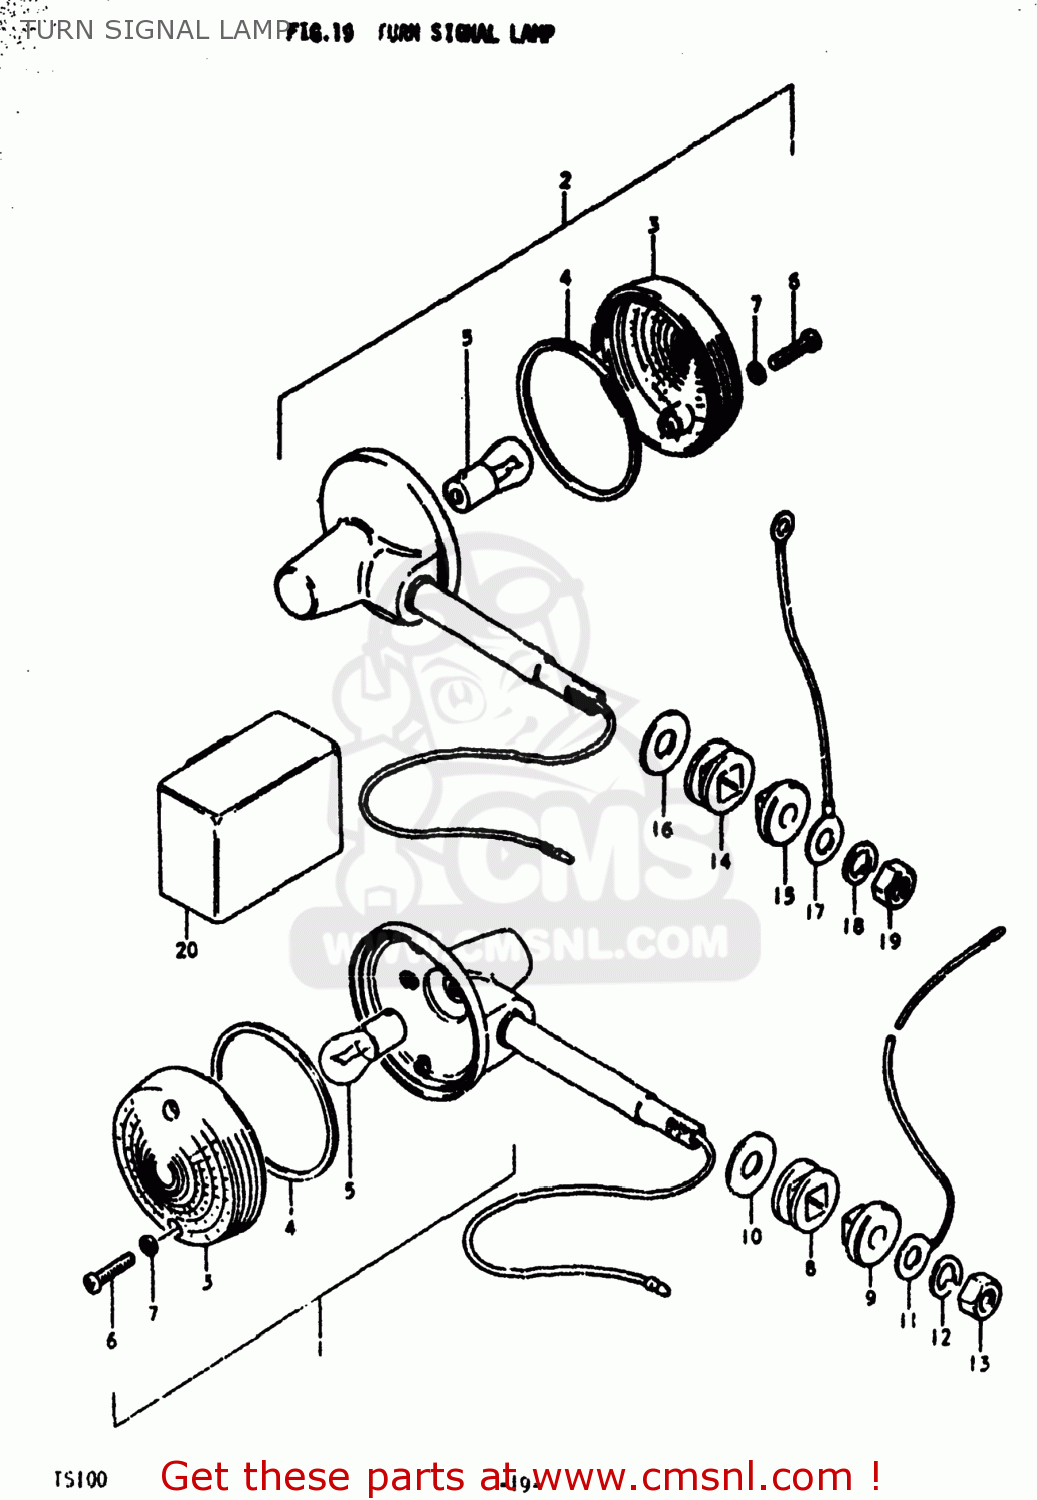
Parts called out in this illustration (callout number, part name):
1	LAMP ASSEMBLY,FRONT TURN SIGNAL
2	LAMP ASSEMBLY,REAR TURN SIGNAL
3	LENS
4	GASKET (NAS)
5	BULB(6V17W,STANLEY,A4513A)
6	SCREW
7	GASKET (NAS)
8	CUSHION
9	SPACER,RR TURNSIGNAL LAMP
10	WASHER (10.5X30X2.3)
11	LEAD WIRE,EARTH
12	LOCK WASHER
13	NUT
14	CUSHION
15	SPACER,RR TURNSIGNAL LAMP
16	WASHER (10.5X30X2.3)
17	LEAD WIRE
18	LOCK WASHER
19	NUT
